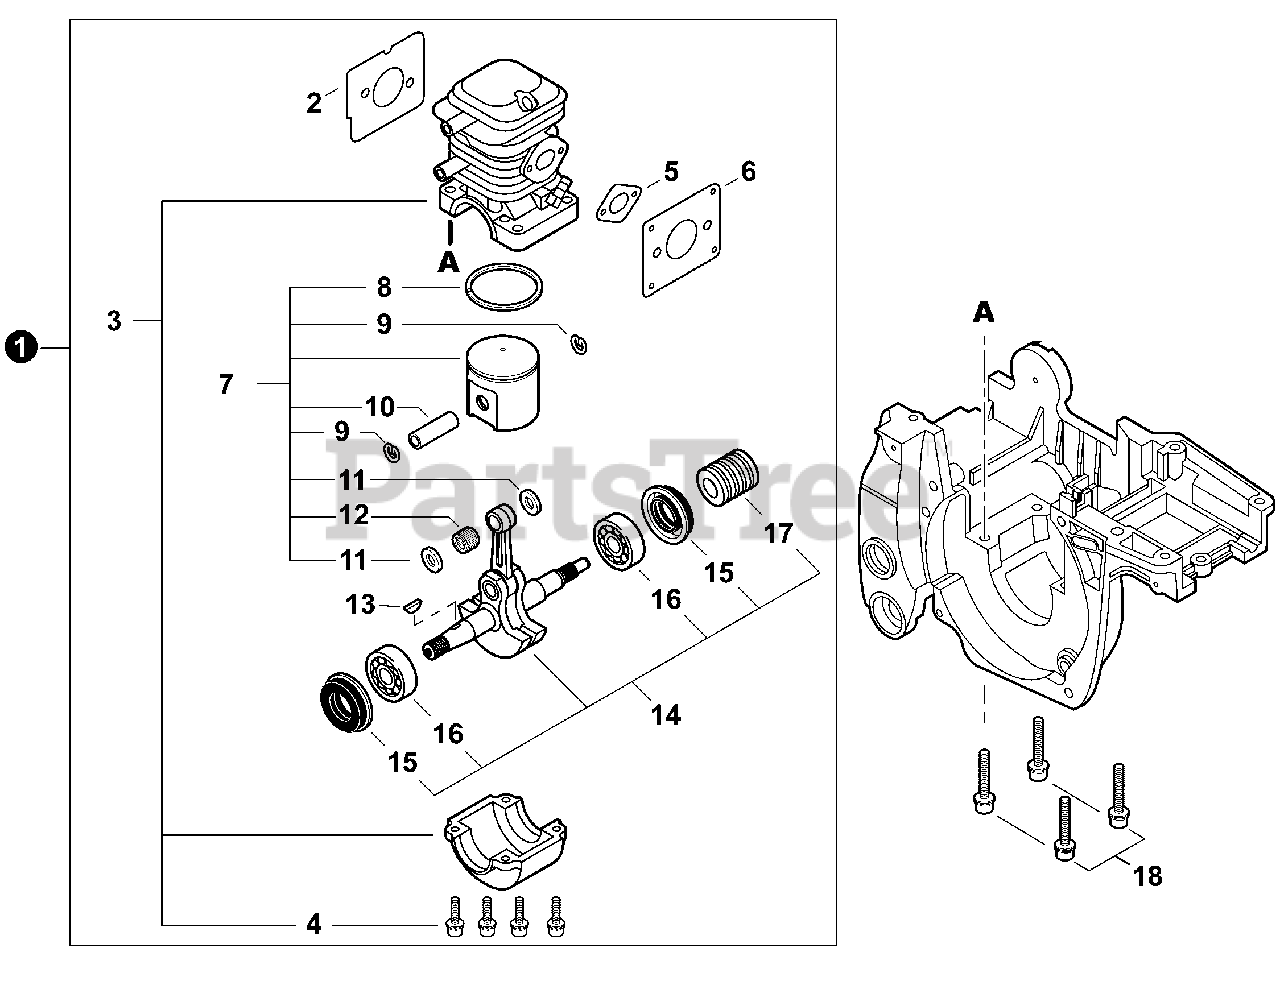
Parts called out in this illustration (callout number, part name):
1	SHORT BLOCK
2	GASKET, EXHAUST
3	CRANKCASE SET
4	BOLT 5×22
5	GASKET, INTAKE
6	GASKET, INTAKE
7	PISTON KIT
8	RING, PISTON
9	RING, SNAP
10	PIN, PISTON
11	WASHER, THRUST
12	BEARING, NEEDLE 9
13	KEY, WOODRUFF
14	CRANKSHAFT ASSY
15	SEAL, OIL 12
16	BEARING, BALL 6201
17	GEAR, WORM
18	BOLT 5×30
